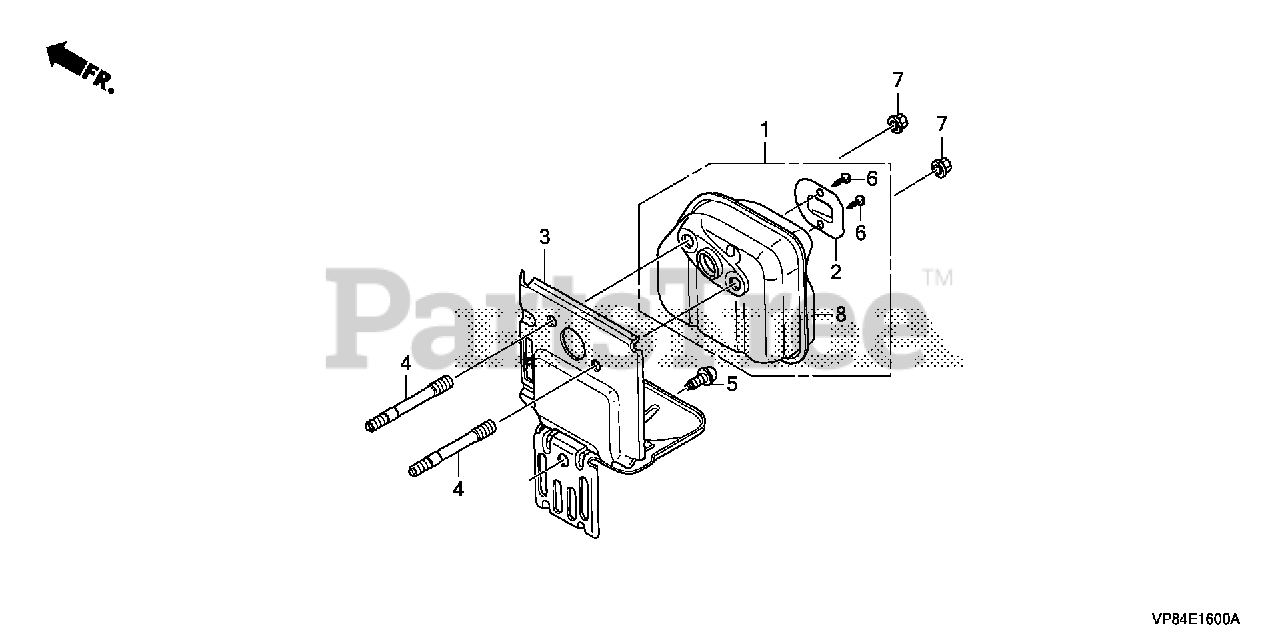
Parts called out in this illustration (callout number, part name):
1	MUFFLER
2	ARRESTER, SPARK
3	GUIDE, AIR EX.
4	BOLT, STUD (5X52)
5	BOLT, SOCKET (5X10)
6	SCREW, TAPPING (4X6) (TO INSTALL OPTIONAL SPARK ARRESTER)
7	NUT, SELF-LOCK (5MM)
